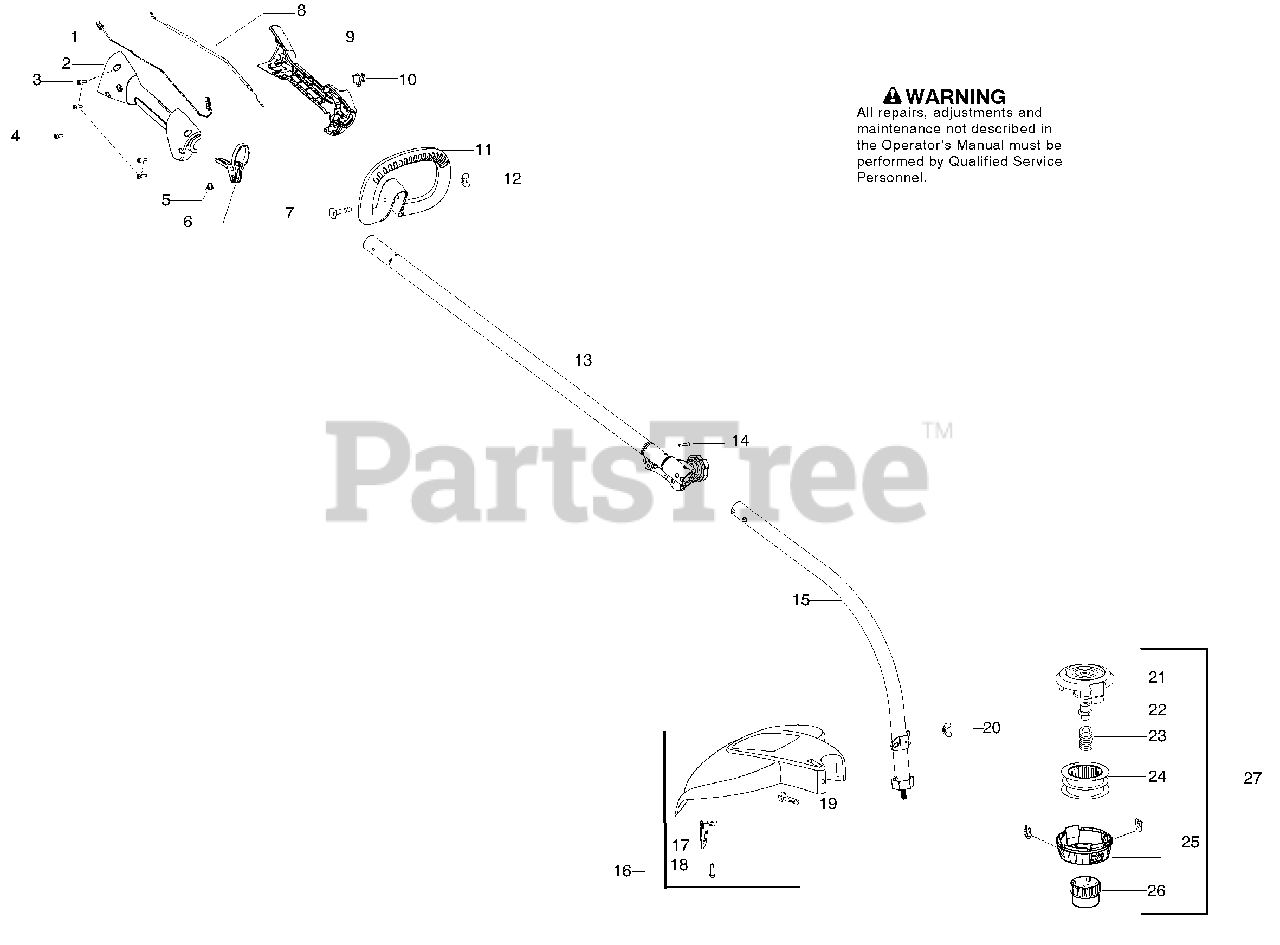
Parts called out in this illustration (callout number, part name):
1	Assy-Switch Wire
2	Housing-Throttle (RH)
3	Screw M4 x 1.75
4	Screw 10-14 x 1/2
5	Spring-Trigger
6	Kit - Trigger
7	Bolt - 1/4-20 x 2
8	Assy - Throttle Cable
9	Housing-Throttle (LH)
10	Kit-Switch
11	Assy - Handle Assist
12	Wingnut - 1/4-20
13	Kit-Driveshaft Upper (Incl.#14)
14	Screw - 12-24 x .480
15	Kit-Driveshaft Lower
16	Kit-Shield
18	Screw - 10-14 x 3/4
19	Bolt - 1/4-20 x 1-1/4
20	Wingnut - 1/4-20
23	Spring
25	Kit - Cover and Eyelet
26	Knob
27	Accy. - TNG 7 Cutting Head
45	Kit-Oil Pump
46	Gear-Worm Spring
47	Elbow-Oil Pickup
50	Assy-Oil-Pickup
